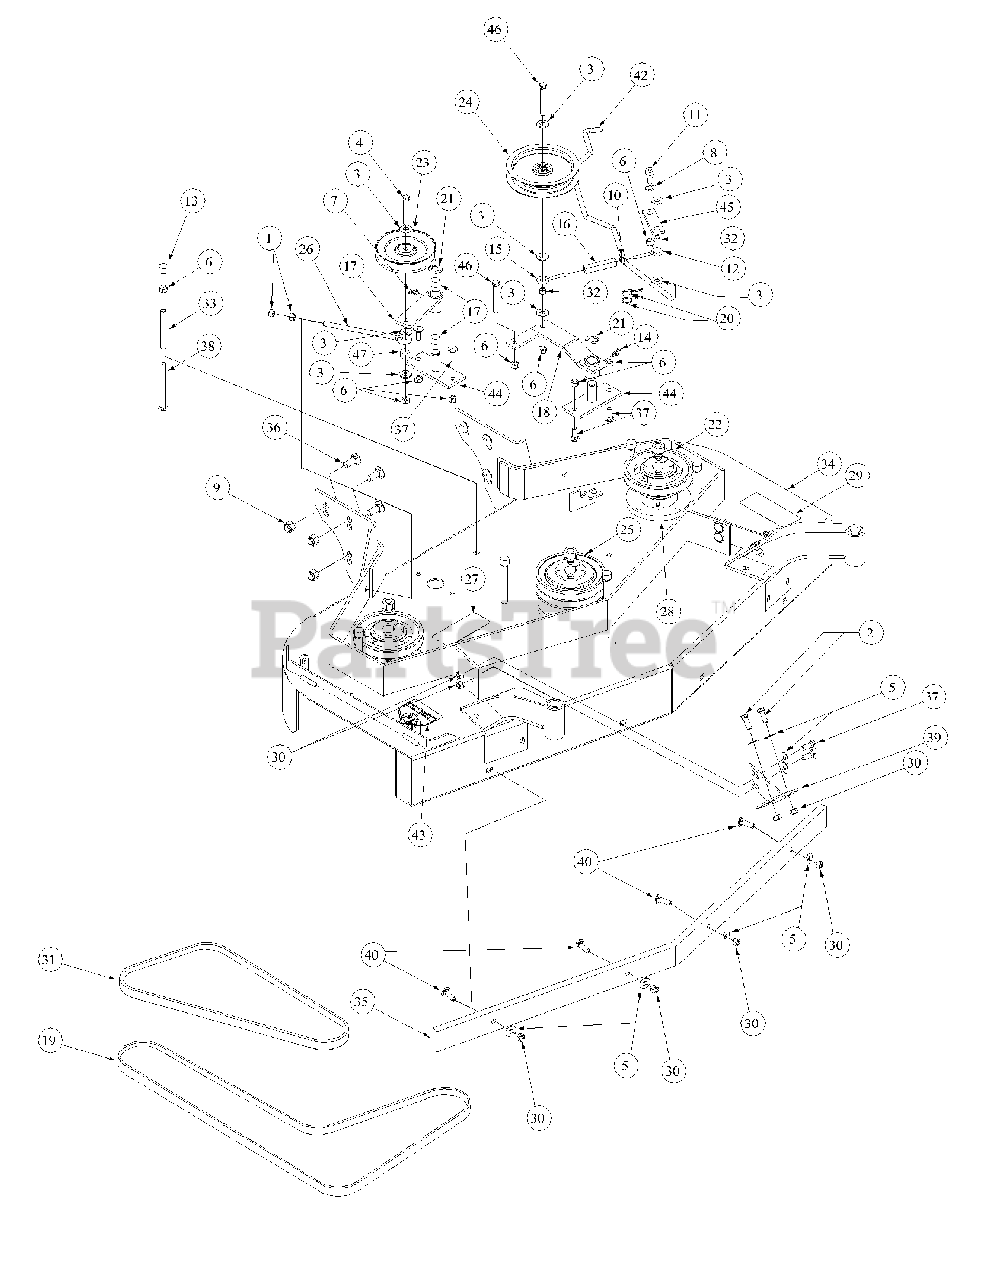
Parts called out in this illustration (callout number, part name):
1	Hex Nut, 3/8-16
2	Hex Cap Screw, 3/8-16, 1
3	Flat Washer, 3/8 Zinc
4	Hex Cap Screw, 3/8-16, 1
5	Flat Washer, 3/8 Zinc
6	Lock Nut, Nylon Insert, 3/8-16
7	Grease Fitting, 1/4-28, 90°.
8	Shim Washer
9	Lock Nut, Nylon Insert, 1/2-13
10	Hex Nut, 5/16-18
11	Shoulder Bolt
12	Eye Bolt, Right Hand
13	Vinyl Cap
14	Grease Fitting, 1/4-28, 45°.
15	Eye Bolt, Left Hand
16	Turnbuckle
17	Idler Arm "B"
18	Idler Arm "A"
19	Drive Belt
20	Hair Pin, 3/8"-1/2"
22	Deck Pulley
23	Idler Pulley
24	Idler Deck Take-up
25	Double Pulley
26	Rod Belt Tensioner
27	Decal Warning Shield Missing
28	Spindle Backing Plate
29	Decal Rotating Blade
30	Lock Nut, Metal, 3/8-16
31	Drive Belt
32	Sleve Turnbuckle
33	Spacer Belt Guide
34	Deck Weldment Mower
36	Carriage Bolt, 1/2-13 x 1-1/4
37	Carriage Bolt, 3/8-16 x 2
38	Carriage Bolt, 3/8-16 x 4-1/2
39	Caster Support Assembly
40	Carriage Screw, 3/8-16 x1-1/2
42	Rod Clutch Link
43	Decal, Danger Hands and Feet
44	Idler Base
46	Hex Cap Screw, 3/8-16, 2.75
47	Sleeve Tensioner
